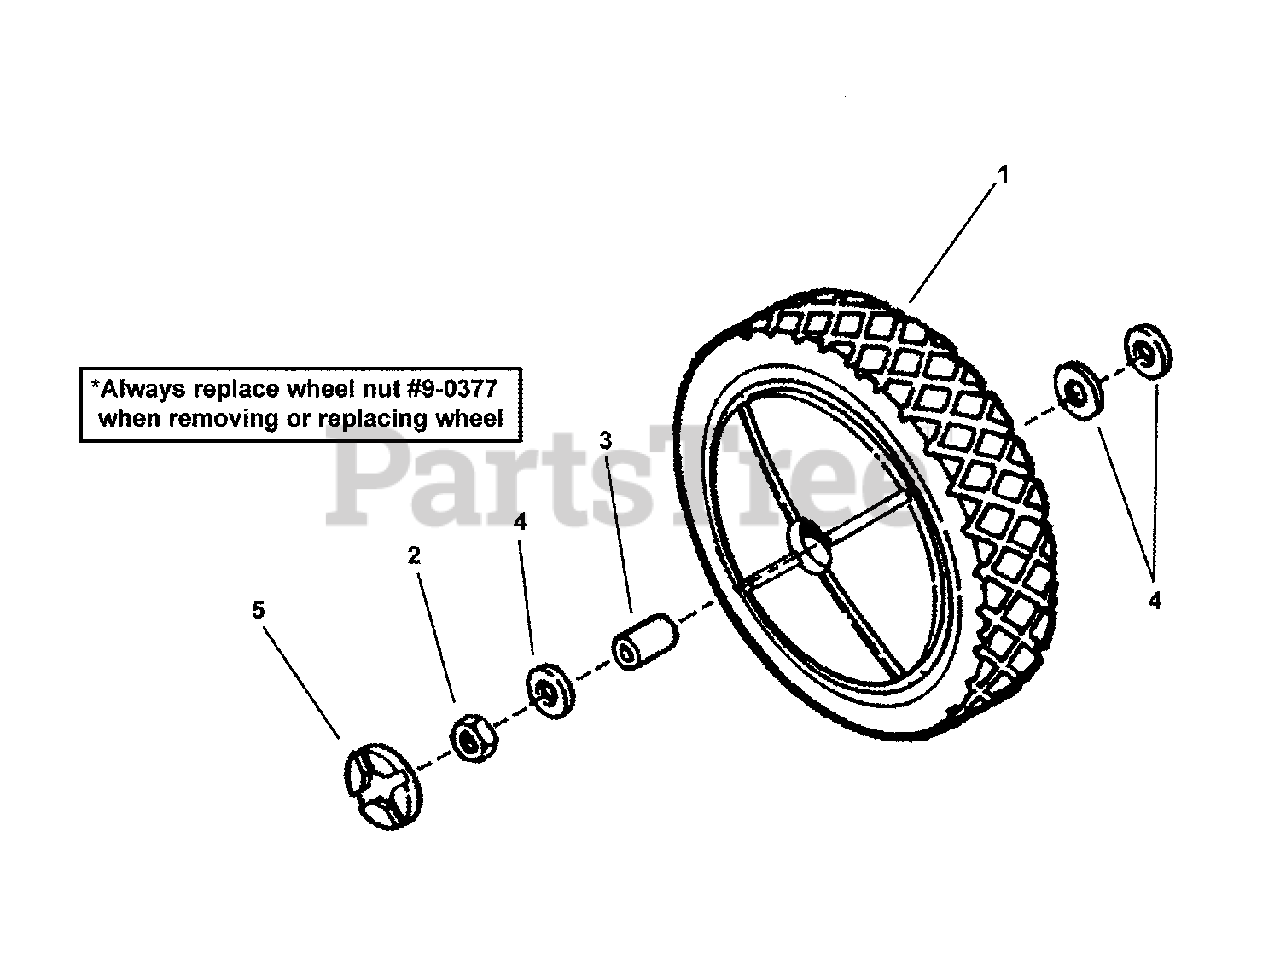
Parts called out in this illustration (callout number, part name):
1	WHEEL, 8 x 1.75 Plastic
2	NUT, 7/16-20 Hex Center Lock Jam
3	BUSHING, Axle
4	WASHER, 7/16" Flat
5	PLUG, Wheel
